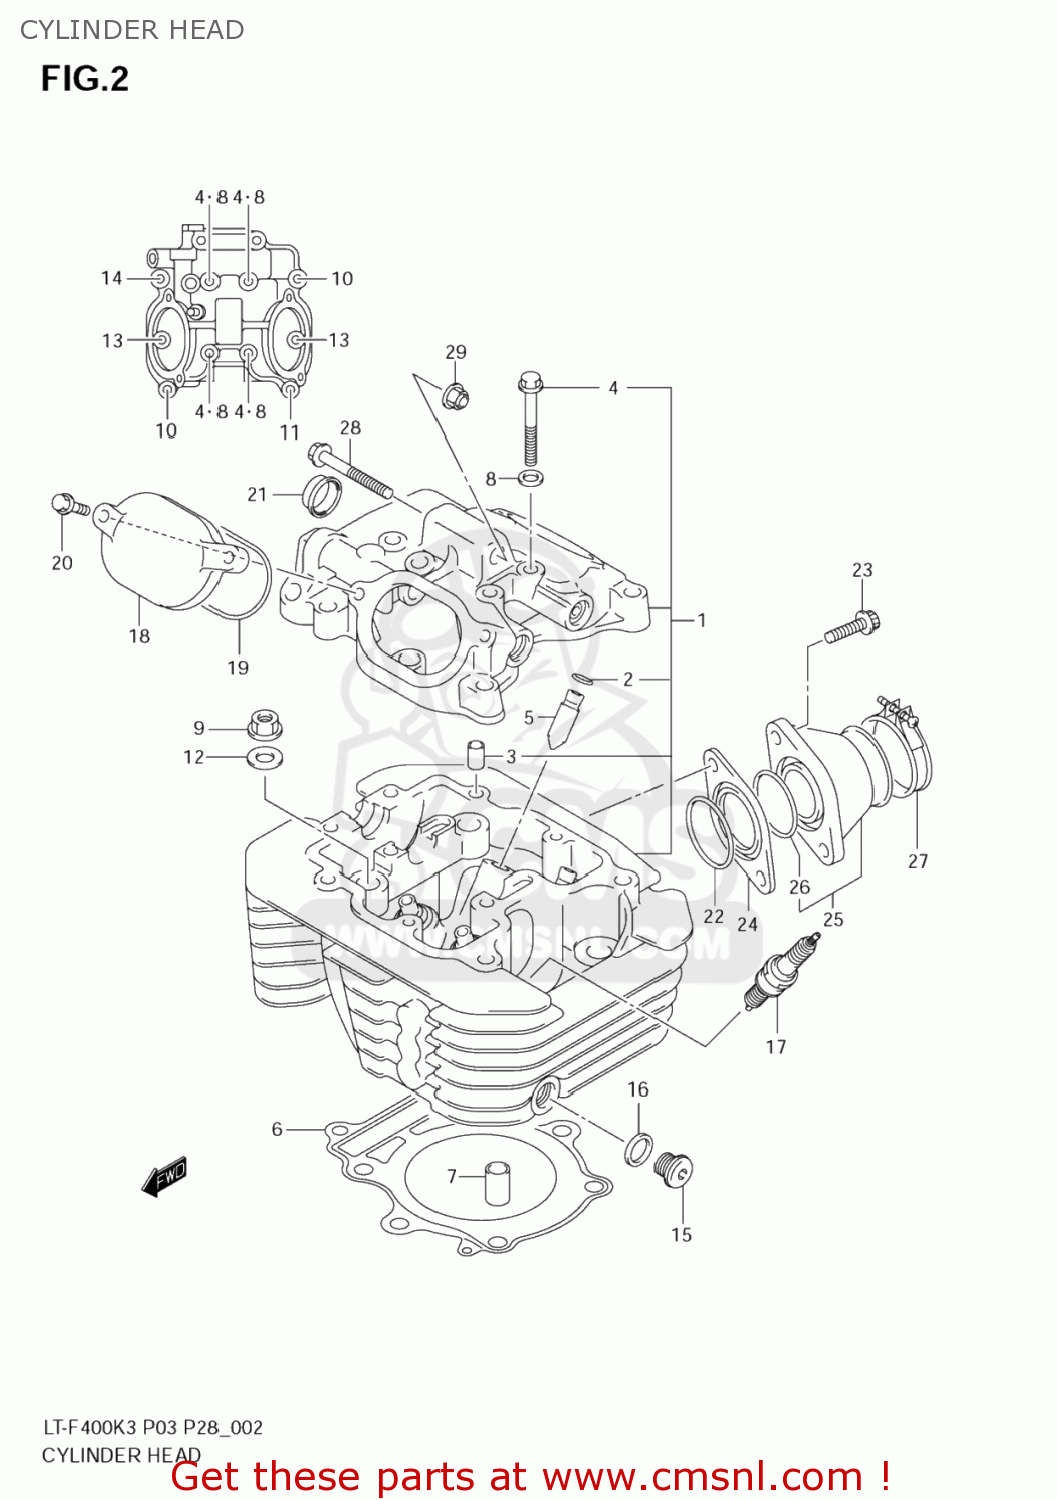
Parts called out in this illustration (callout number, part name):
1	HEAD ASSY,CYLI
2	RING,SNAP
3	PIN(6.2X8X11)
4	BOLT(6X55)
5	GUIDE,VALVE
6	GASKET,CYLINDER HEAD (NAS)
7	PIN(10.4X13X22)
8	GASKET(5.8X13X1.2) (NAS)
9	NUT
10	BOLT(6X35)
11	BOLT(6X39)
12	WASHER (10.5X22X2.3)
13	BOLT
14	BOLT
15	PLUG(L:12)
16	GASKET(12.1X16.2X3.7) (NAS)
17	PLUG,SPARK(CR7E)
18	CAP,INSPECTION
19	O RING,INSPECTION CAP
20	BOLT
21	PLUG,OD:30
22	O RING(D:2.4,ID:39.7)
23	BOLT,OIL PAN
24	INSULATOR,INTA
25	PIPE ASSY,INTAKE
26	O RING(D:2.4,ID:39.7)
27	CLAMP
28	BOLT 8X60
29	NUT
